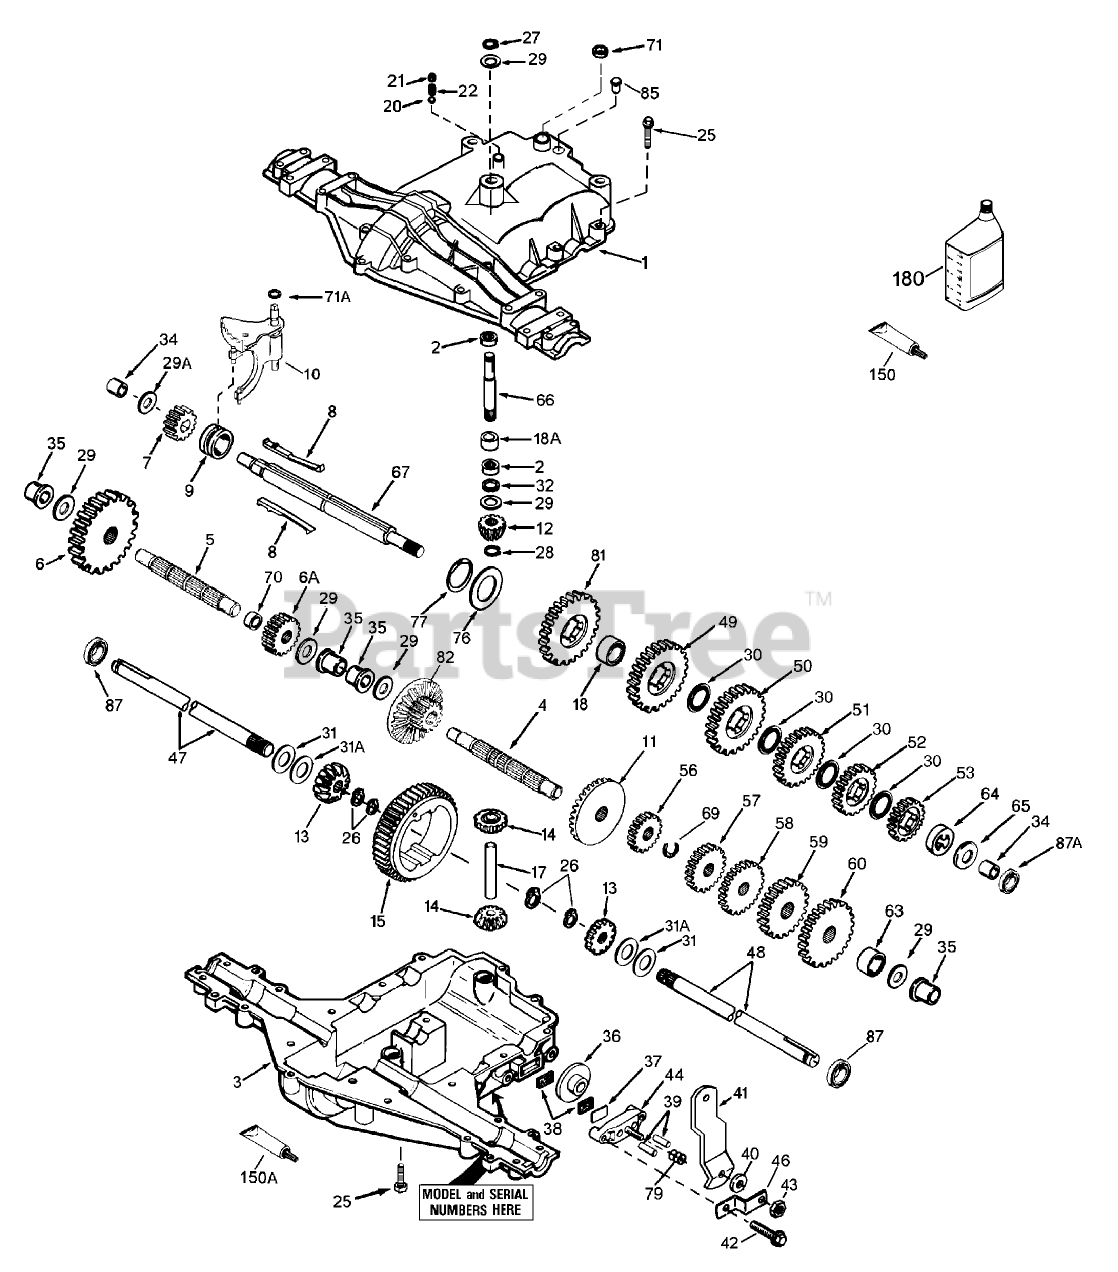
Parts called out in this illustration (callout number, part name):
1	Transaxle Cover
2	Bearing-Needle
3	Transaxle Case
4	Countershaft
5	Output Shaft
6	Spur Gear (38 teeth)
6A	Spur Gear (15 teeth-steel)
7	Spur Gear (11 teeth-steel)
8	Shift Key
9	Shift Collar
10	Shift Rod Fork
11	Bevel Gear (30 teeth)
12	Input Bevel Pinion (13 teeth)
13	Bevel Gear (16 teeth-steel)(Incl. 13)
14	Bevel Gear (16 teeth-steel)(Incl. 13)
15	Ring Gear (43 teeth)
17	Drive Pin
18	Spacer
18A	Spacer
20	Ball-Steel
21	Screw-Set
22	Spring
25	Ring Set (.020 O S)
26	Retaining Ring (pkg of 2)
27	Ring-Snap
28	Ring-Retainer
29	Washer
29A	Washer
30	Washer
31	Washer
31A	Flat Washer (.062 wide)
32	Oil Seal
34	Bushing
35	Flanged Bushing
36	Brake Disk
37	Brake Pad Plate
38	Pad-Brake 2/Pkg
39	Dowel Pin
40	Washer
41	Brake Lever
42	Ring Set (.020 O S)
43	Locknut
44	Nozzle-Carburetor
46	Bracket
47	Axle (11-15/16" long)
48	Axle (16-1/2" long)
49	Spur Gear (29 teeth-steel)
50	Spur Gear (23 teeth-steel)
51	Spur Gear (20 teeth)
52	Spur Gear (16 teeth-steel)
53	Spur Gear (15 teeth-steel)
56	Spur Gear (11 teeth-steel)
57	Spur Gear (17 teeth-steel)
58	Spur Gear (20 teeth)
59	Spur Gear (24 teeth-steel)
60	Spur Gear (25 teeth)
63	Spacer
64	Spacer
65	Washer
66	Input Shaft
67	Shifter Brake Shaft
69	Retaining Ring
70	Spacer
71	Cut Seal-Square
71A	O Ring
76	Washer
77	Inverted Retaining Ring
79	Piston ASM (.020 O S)
81	Spur Gear (27 Teeth)
82	Bevel Spur Gear (30 13 teeth)
85	Pipe Plug
87	Oil Seal
87A	Oil Seal
150	Liquid Gasket RTV Silicone
150A	Liquid Gasket Loctite #242
180	Gear Oil
